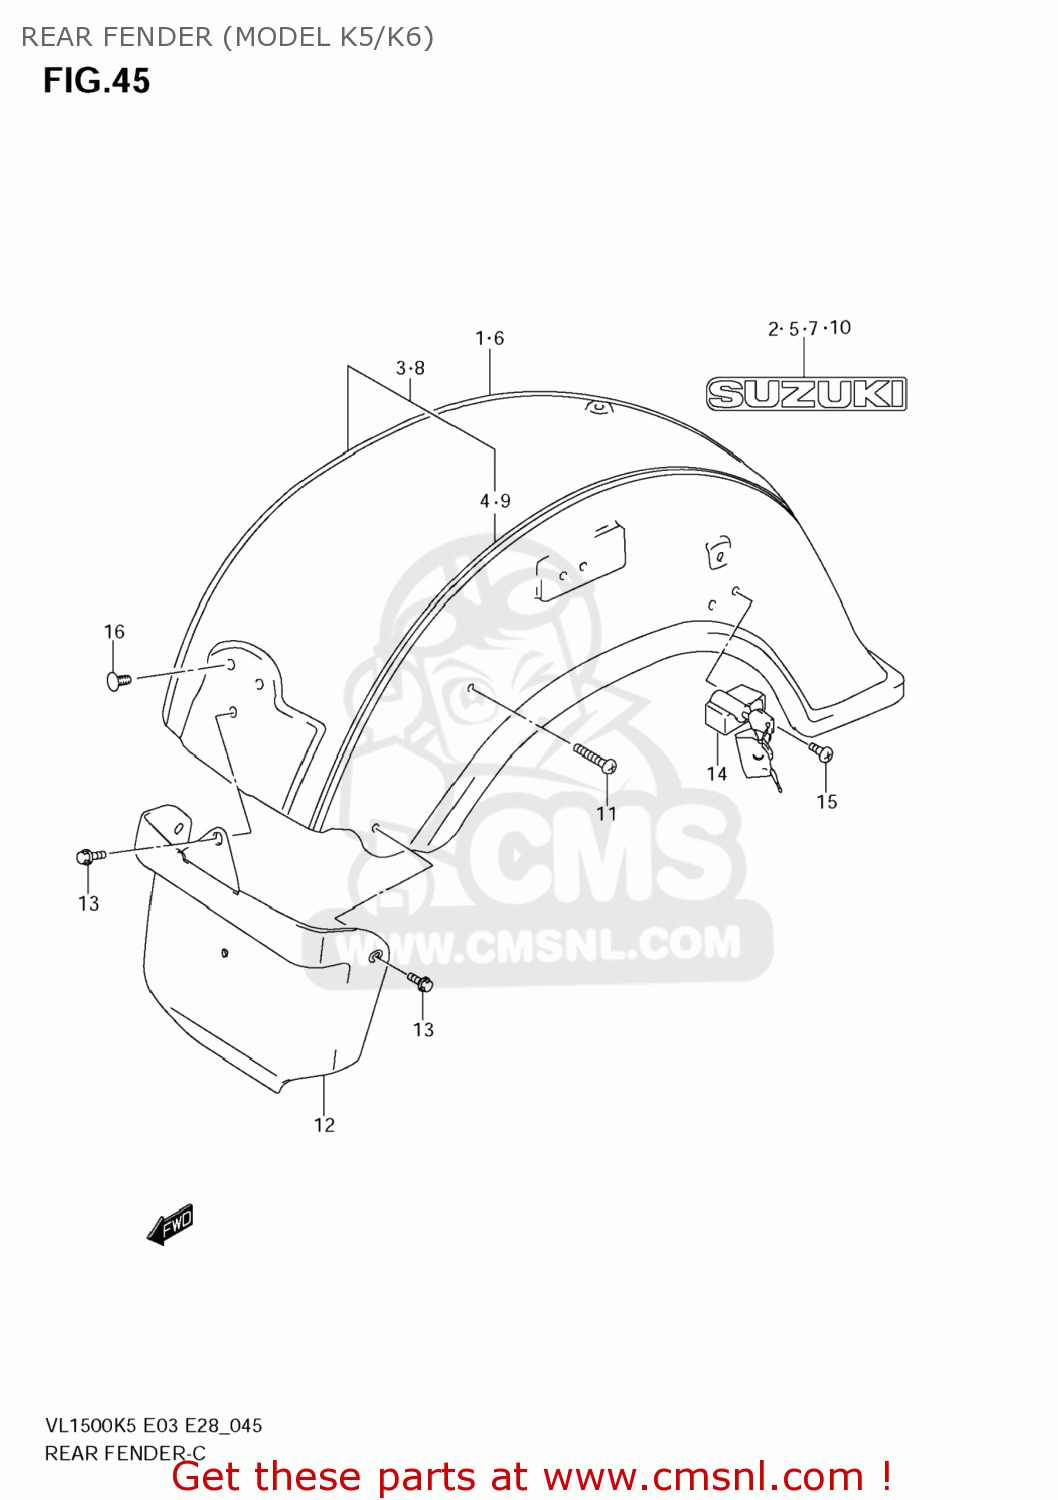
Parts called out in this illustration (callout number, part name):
1	FENDER ASSY,RR
2	EMBLEM,SUZUKI
3	FENDER ASSY,RR
4	TAPE SET,RR FENDER
5	EMBLEM,SUZUKI
6	FENDER ASSY,RR
7	EMBLEM,SUZUKI
8	FENDER ASSY,RR
9	TAPE SET,RR FENDER
10	EMBLEM,SUZUKI
11	BOLT(8X37)
12	MUDGUARD,RR FENDER FR
13	BOLT(6X16)
14	LOCK SET,HELMET
15	SCREW(6X14)
16	CAP(OD:12)
